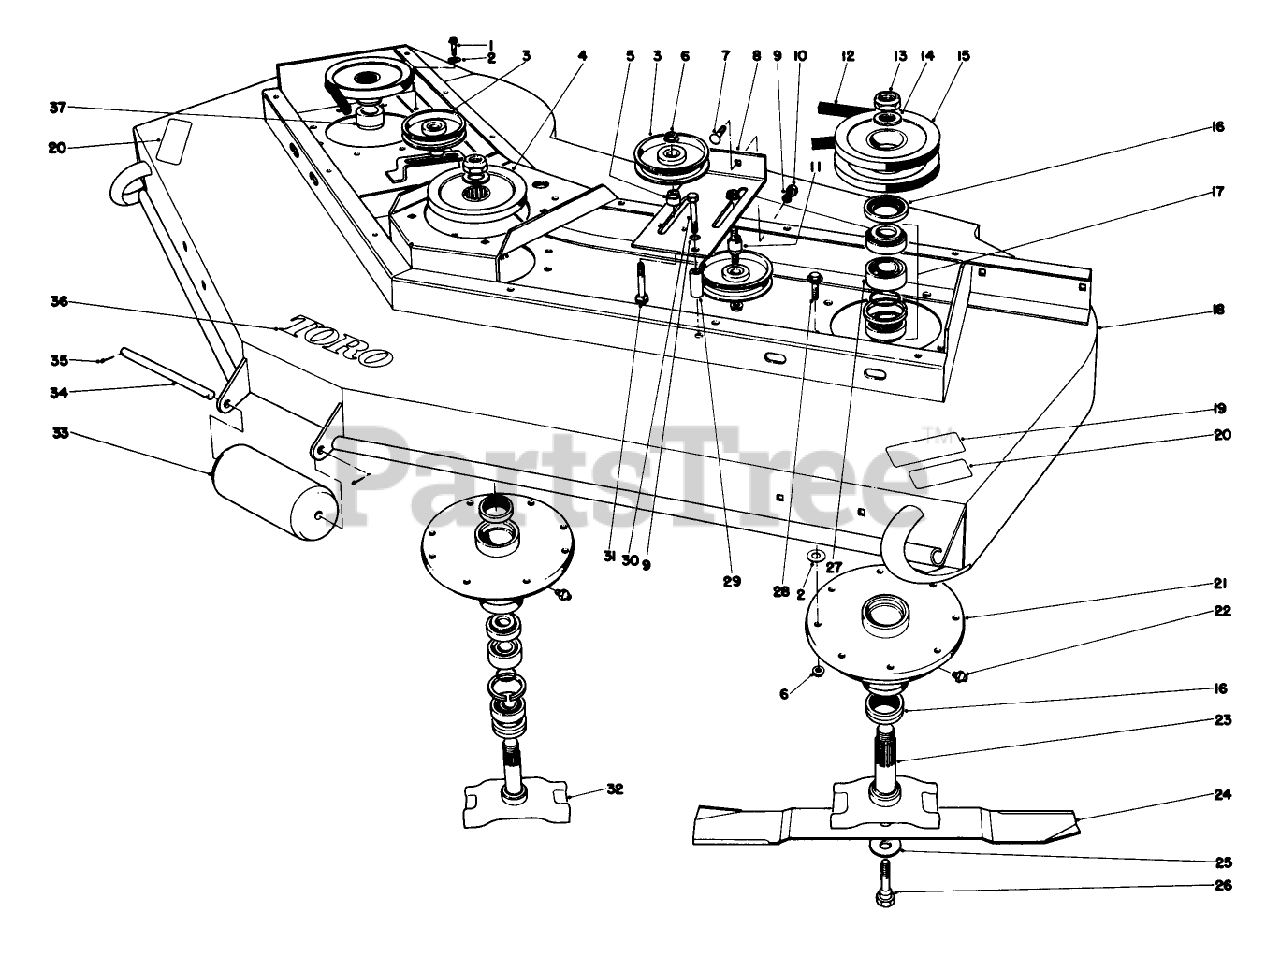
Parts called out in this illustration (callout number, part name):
1	SCREW-HHF
2	WASHER-FLAT
3	PULLEY-IDLER
4	PULLEY AND HUB ASM
5	SPACER-IDLER PULLEY
6	NUT-HF
7	SCREW-CARR
8	Idler Mount L.H.
9	WASHER-LOCK
10	NUT-HEX
11	STUD-IDLER
12	V-BELT
13	NUT-LOCK, NI
14	WASHER-THRUST
15	PULLEY-L.H. W.A.
16	SEAL-OIL
17	BEARING KIT (MATCHED SET)
18	Cutter Deck
19	Decal-Caution
20	DECAL-CAUTION, BLADE
21	Spindle Housing
22	FITTING-GREASE
23	OUTER SPINDLE WA
24	BLADE-STANDARD, LH, 25IN
25	WASHER-BELLEVILLE
26	CAPSCREW
27	Spacer Matched Set
28	SCREW-HHF
29	SPACER-IDLER MOUNT
30	SCREW-HH
31	SCREW-CARR
32	Spindle Ctr.
33	ROLLER-FRONT
34	ROLLER SHAFT
35	PIN-COTTER
36	TORO LOGO DECAL
37	Spacer R.H.Spindle
